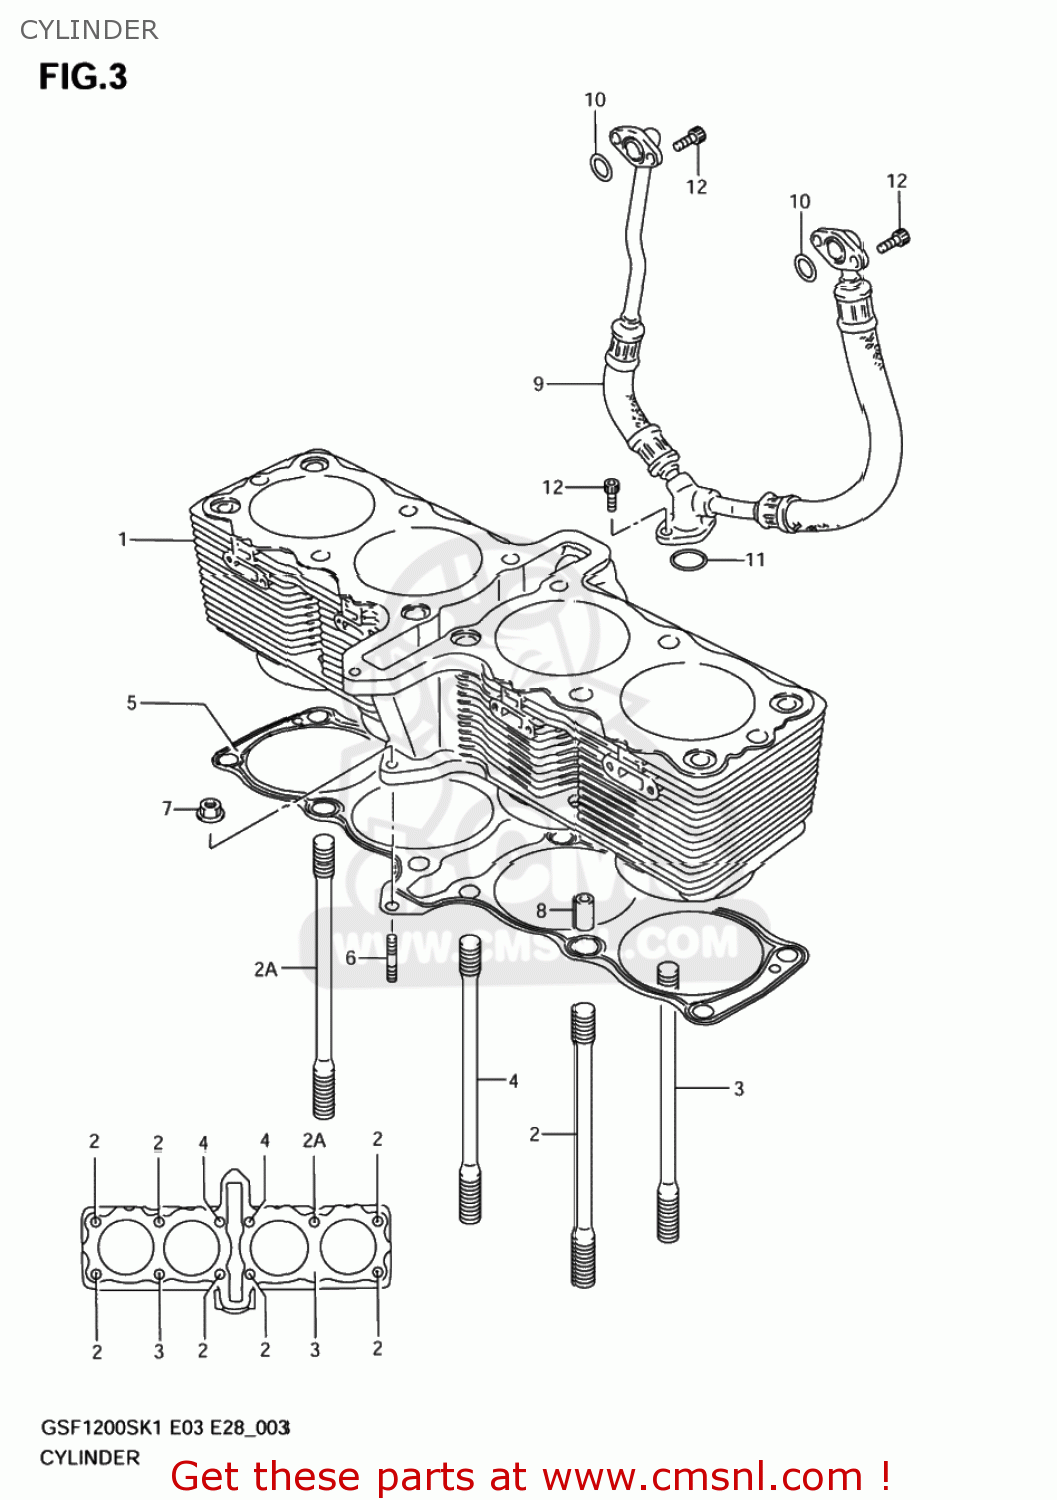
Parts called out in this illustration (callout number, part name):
1	CYLINDER
2	BOLT,STUD
2A	BOLT,STUD
3	BOLT,STUD
4	BOLT,STUD
5	GASKET,CYLINDER (NAS)
6	STUD,M6X1X32
7	NUT
8	PIN(13X10.4X20)
9	HOSE,OIL HEAD COOLER
10	O RING(D:2.5,ID:13.8)
11	O RING(D:2.4,ID:15.8)
12	BOLT,OIL FILLE
